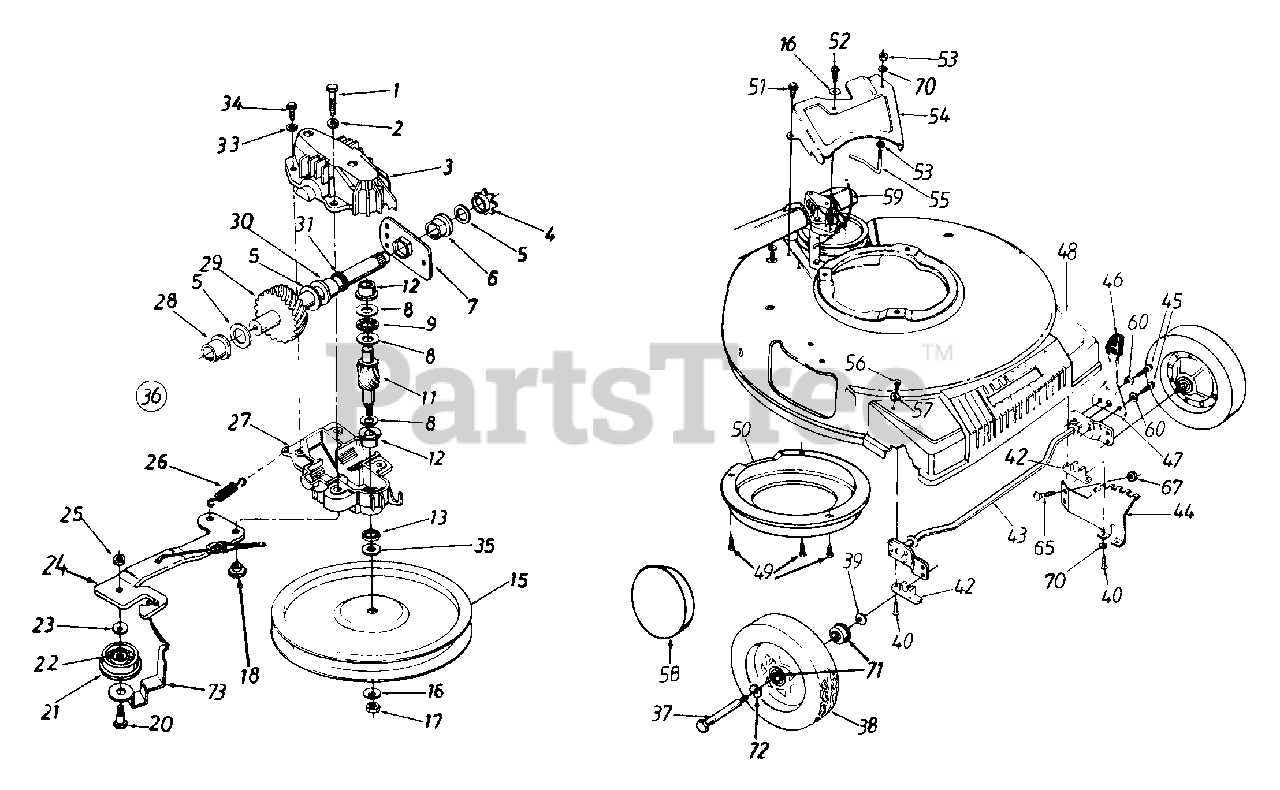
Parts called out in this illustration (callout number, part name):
1	Hex Patch Bolt 1/4-20 x 1.25"
2	L-Wash. 1/4" I.D.
3	Upper Hsg. Half
4	#48 Sprocket 7 T x 1/2 Pitch
5	Fl-Wash. 5/8" I.D. x .030
6	Hex Flange Brg..631" I.D.
8	Thrust Wash..382" I.D. x .70" O.D.
9	Thrust Bearing .375" I.D. x .812" O.D.
11	11 Tooth Pinion Shaft
12	Flange Bearing
13	Oil Seal
15	Fl-Pulley 5.06" O.D.
16	Bell-Wash..265" I.D. x.75"
17	Hex L-Nut 1/4-28 L.H. Thd.
18	Shld. Spacer .375" Dia. x .170
20	Shld. Bolt .375" Dia. x .40"
21	Fl-Idler Plastic 1.50" Dia.
22	Needle Brg..375" x .31
24	Idler Brk't. Ass'y.
25	Hex Patch L-Nut 1/4-28 Thd.
26	Extension Spring 1.12" Lg.
27	Lower Hsg. Half
28	Flange Bearing .566 Dia.
29	Shaft Ass'y.
30	Flange Bearing .629 Dia.
31	Oil Seal .625 Dia.
33	L-Wash. #10 I.D.
34	Hex B-Tap Scr. #10 x .62"
35	Hex Washer .26" x .88"
36	Transmission Comp.
37	Front Axle Bolt
38	Wheel Ass'y. Comp.
39	Bell-Wash..380" I.D. x .88
40	Hex Wash. Hd. Scr. 1/4 x 1" Lg.
42	Block Bushing
43	Axle Ass'y.
44	Height Adj. Bracket
45	Hex TT-Tap Scr. 1/4-20 x .38"
46	Knob
47	Spring Lever
48	Plastic Front End
49	Hex 8-Tap Scr. 1/4" x .38"
50	Belt Cover
51	Hex Wash. Hd. TT-Scr. 1/4-20
52	Hex Wash. Hd. B-Tap Scr. 1/4 x .62" (Spec.)
53	Hex Nut 1/4-20 Thd.
56	Torx Truss Hd. Scr. 5/16 x .75"
57	Bell-Wash..345" I.D. x .88"
58	Hub Cap
59	S.P. Cable
60	External L-Wash. 1/4" I.D.
65	Carr. Bolt 1/4-20 x .5" Lg.
67	Hex Flange L-Nut 1/4-20 Thd.
70	L-Wash. 1/4" I.D.
71	Wheel Bearing
72	Wave Washer
73	Belt Keeper
